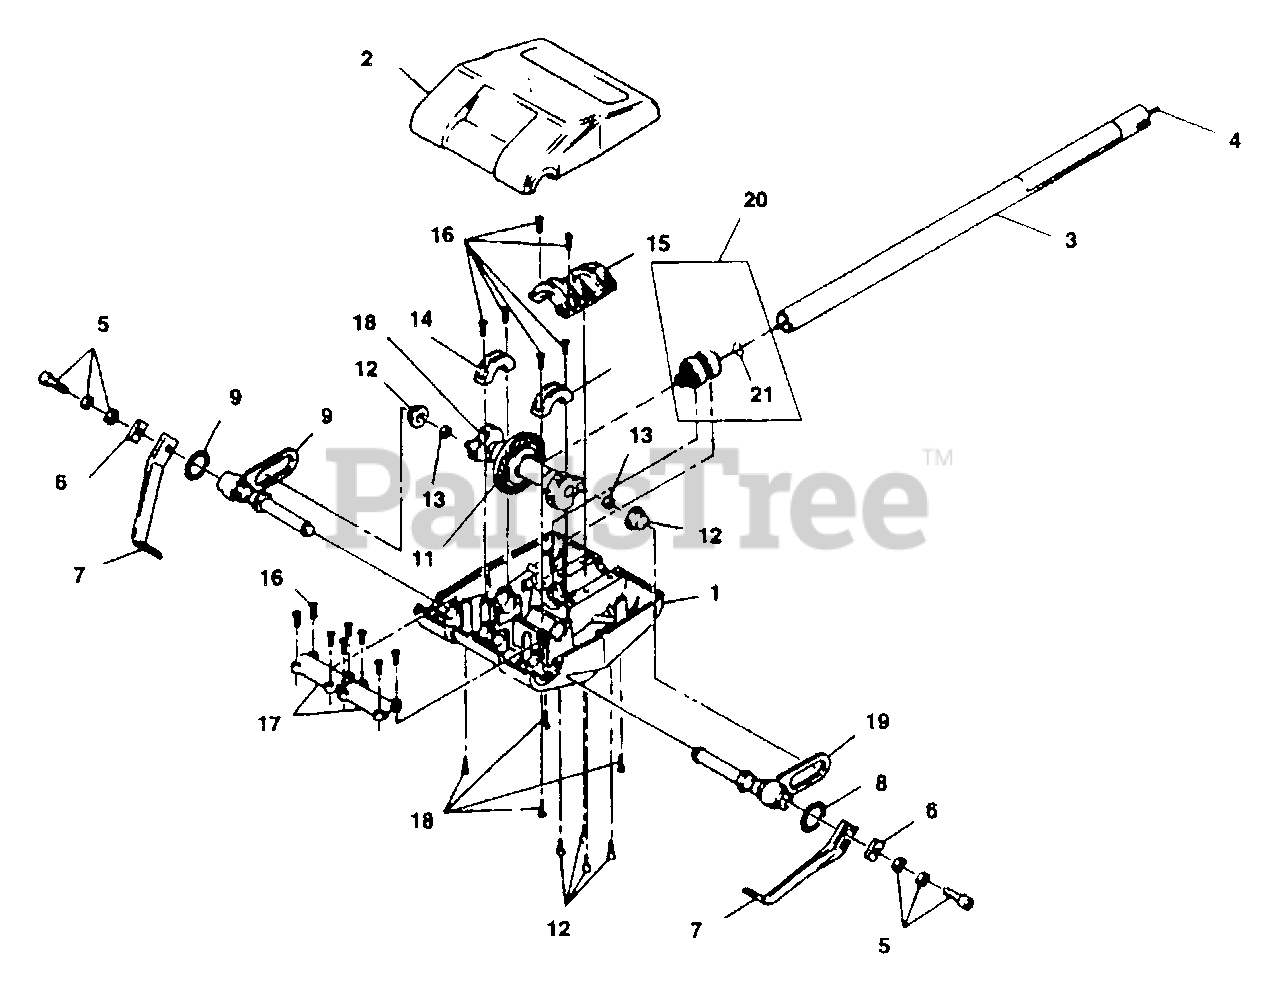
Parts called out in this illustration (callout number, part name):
1	LOWER COVER
2	UPPER HOUSING
3	DRIVE SHAFT HOUSING
4	FLEX CABLE
5	BOLT, SEMS
6	TINE SUPPORT
8	"O" RING
9	ROCKER ARM L.H.
11	CRANK ASSY.
12	FLOATING BUSHING
13	WASHER
14	CRANKSHAFT CLAMP
15	SHAFT CLAMP
16	SCREW
17	SHAFT CLAMP
19	ROCKER ARM R.H.
20	PINION GEAR & BEARING
21	SNAP RING
